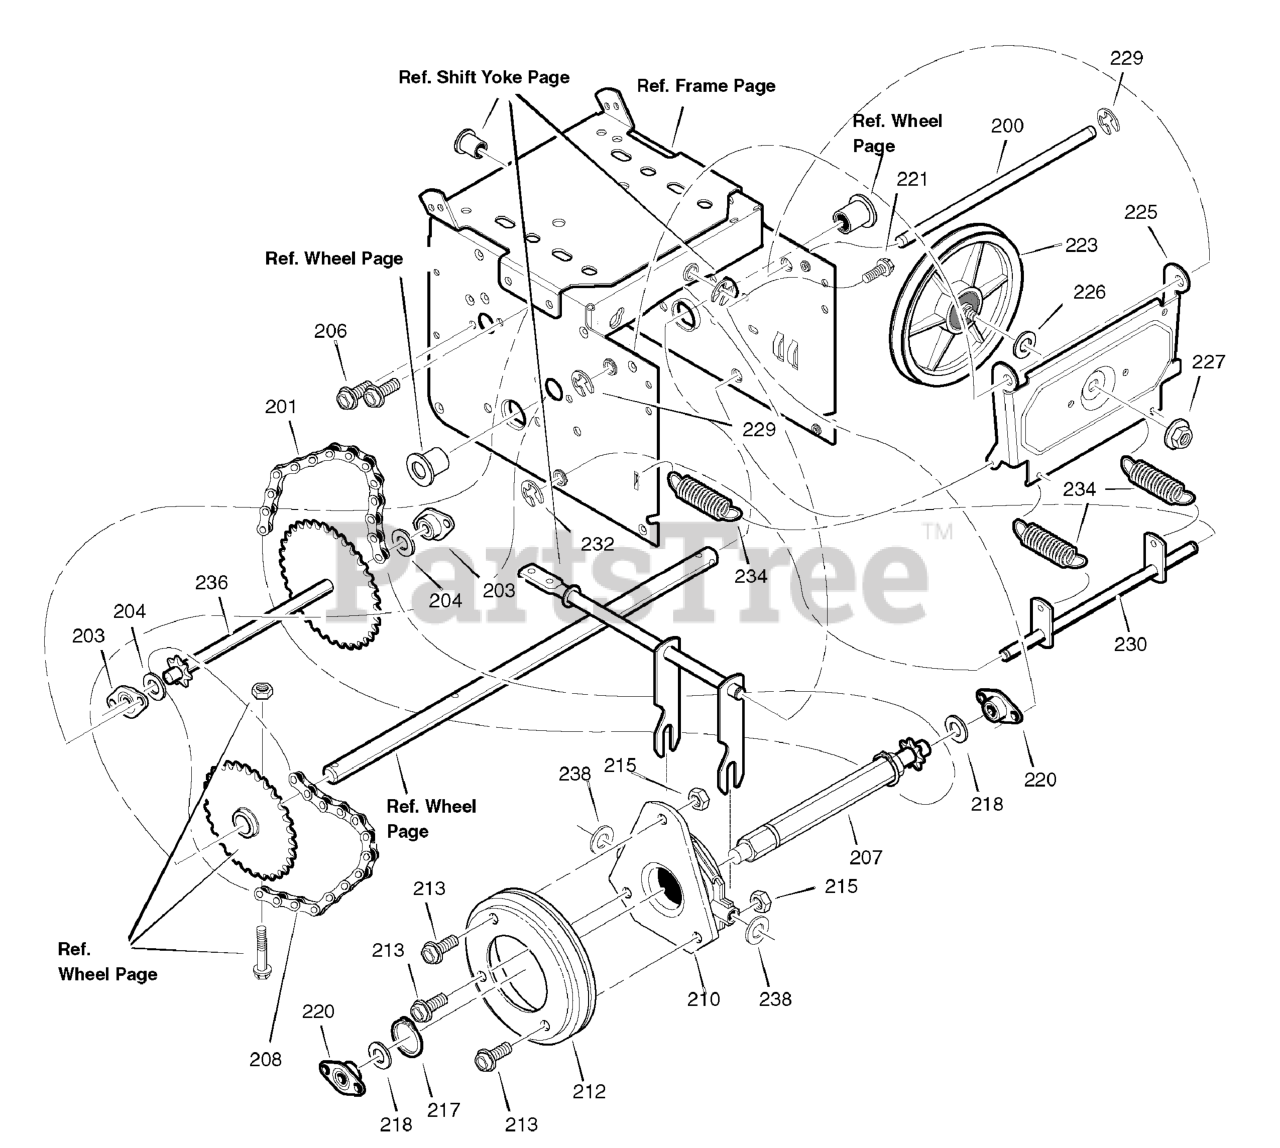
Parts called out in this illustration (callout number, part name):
200	AXLE, Swing Plate
201	CHAIN, Roller, #420 x 19.00
203	BEARING AND RETAINER ASSEMBLY
206	SCREW, TAP 5/16-18 x 1/2
207	ASSEMBLY, Hex Shaft
208	CHAIN, ROLLER, #420 x 18.00 LG
210	BEARING, Trunion Clutch, R
212	WHEEL, Friction Disk
213	BOLT, Hex, 1/4-20 x 5/8
215	NUT, Keps Hex, 1/4-20
217	RING, Retext
218	WASHER, Flat, 1/2
220	BEARING AND RETAINER ASSEMBLY
221	SCREW, Tap 5/16-18 x 1/2
223	FRICTION PULLY
225	PLATE, Swinging
226	SPACER, Friction Pulley
227	NUT, Flange Lock, 3/8-24
229	RETAINER, Ring
230	ASSEMBLY, Leaf Spring Link
232	RETAINER, Ring
234	SPRING, Extension
236	SPROCKET, 33T/7
238	WASHER, Flat
